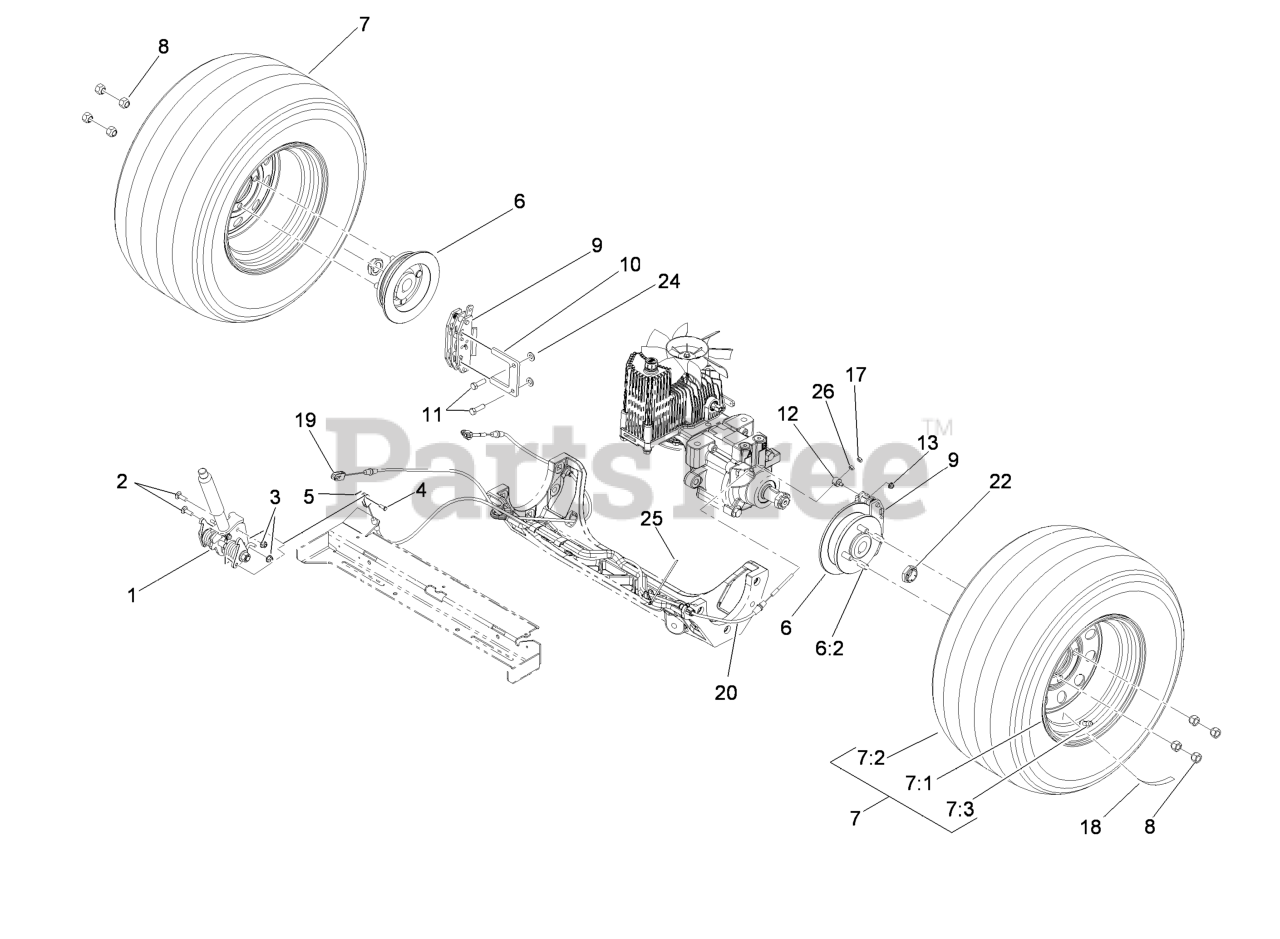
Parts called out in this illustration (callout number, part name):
1	BRAKE HANDLE ASM
2	BOLT-CARR
3	NUT-HF, NI
4	PIN-CLEVIS
5	PIN-COTTER
6	WHEEL HUB ASM
6:2	STUD-WHEEL
7	WHEEL AND TIRE ASM
7:1	RIM ASM
7:2	TIRE
7:3	Stem-Valve
8	NUT-LUG
9	CALIPER-BRAKE
10	PLATE-MOUNT, BRAKE
11	SCREW-LOCK, PATCH
17	NUT-LOCK, NI
22	LOCKNUT
24	WASHER-FLAT
25	TIE-CABLE
26	NUT-HEX
